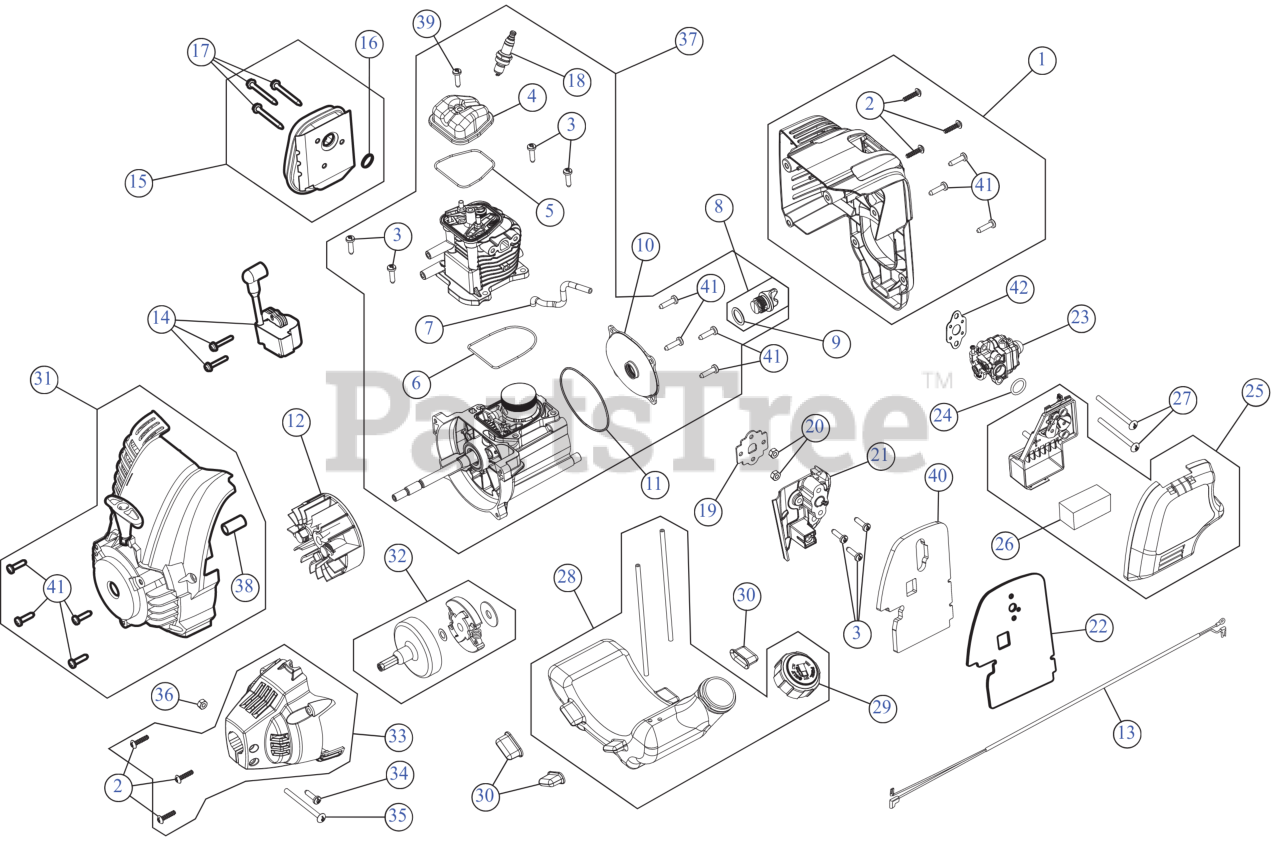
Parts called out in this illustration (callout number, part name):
1	REAR ENGINE CVR
2	SCREW 8-16 x 3/4
3	SCREW, M5 x 18.7MM
4	ROCKER COVER
5	O-RING
6	O-RING CYL AC5
7	HOSE, BREATHER
8	OIL PLUG
9	RING, OIL PLUG (AC
10	CRANKCASE COVER
11	O-RING CRNKCSE CVR
12	FLYWHEEL ASSEMBLY AC3.1
13	LEAD WIRES
14	MODULE
15	MUFFLER ASSEMBLY
16	GASKET/MUFFLER
17	SCREW M5 x 44MM
18	SPARK PLUG 4 CYCL
19	GASKET/INSULATOR
20	NUT 10-32
21	CARB INSULATOR
22	GASKET
23	CARBURETOR AC3.1
25	AIR CLEANER ASSEMBLY
26	AIR FILTER
27	SCREW 10-32X2.5
28	FUEL TANK ASSEMBLY
29	FUEL CAP ASSEMBLY
30	FUEL TANK PADS
31	STARTER HOUSING
32	CLUTCH ASSEMBLY
33	CLUTCH COVER ASSEMBLY
34	SCREW, 8-32 x .312 P
35	SCREW
36	HEX NUT
37	SHORT BLOCK
38	SPACER :2.165"
39	SCR, VALVE COVER
40	HEAT SHIELD
41	SCREW M5-0.8 x 19
42	CARBURETOR GASKET
